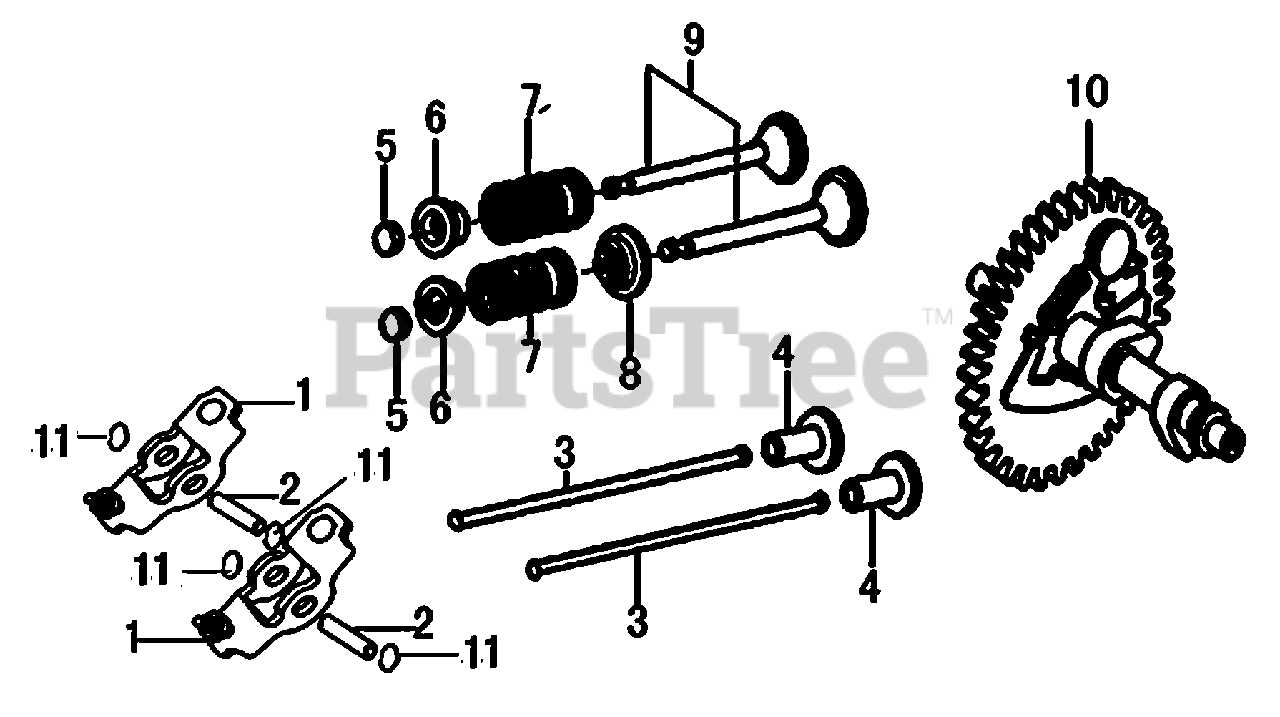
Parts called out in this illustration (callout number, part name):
1	ARM, ROCKER
2	SHAFT, VALVE ROCKER
3	ROD, PUSH
4	VALVE, LIFTER
5	ROTATOR, VALVE
6	RETAINER, VALVE SPRING
7	SPRING, VALVE
8	SEAL, GUIDE
9	VALVE COMP.
10	CAMSHAFT ASSY.
11	SPLIT WASHER
